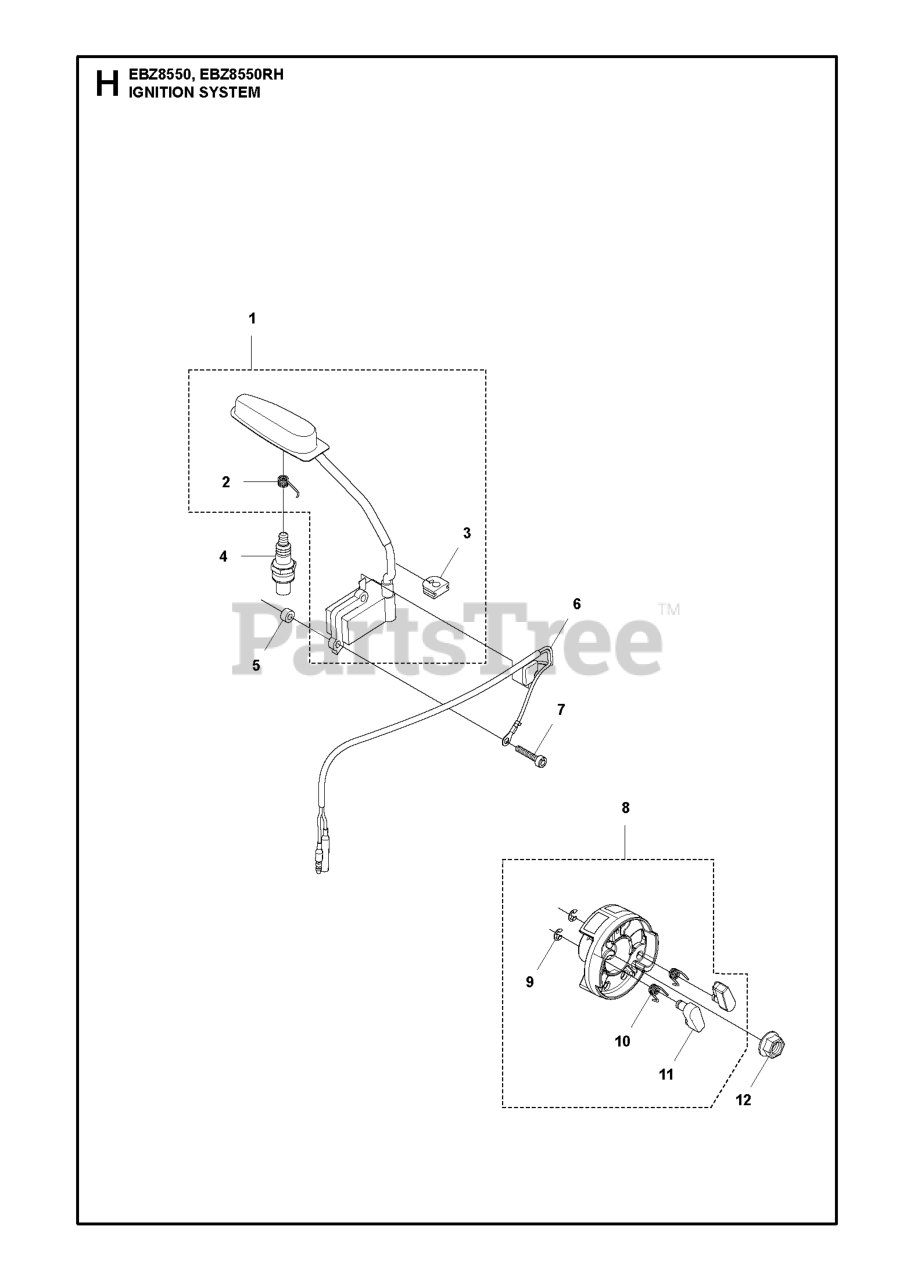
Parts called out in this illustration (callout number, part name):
1	COIL ASSY
3	GROMMET
4	PLUG CMR7H
8	ROTOR ASSY
